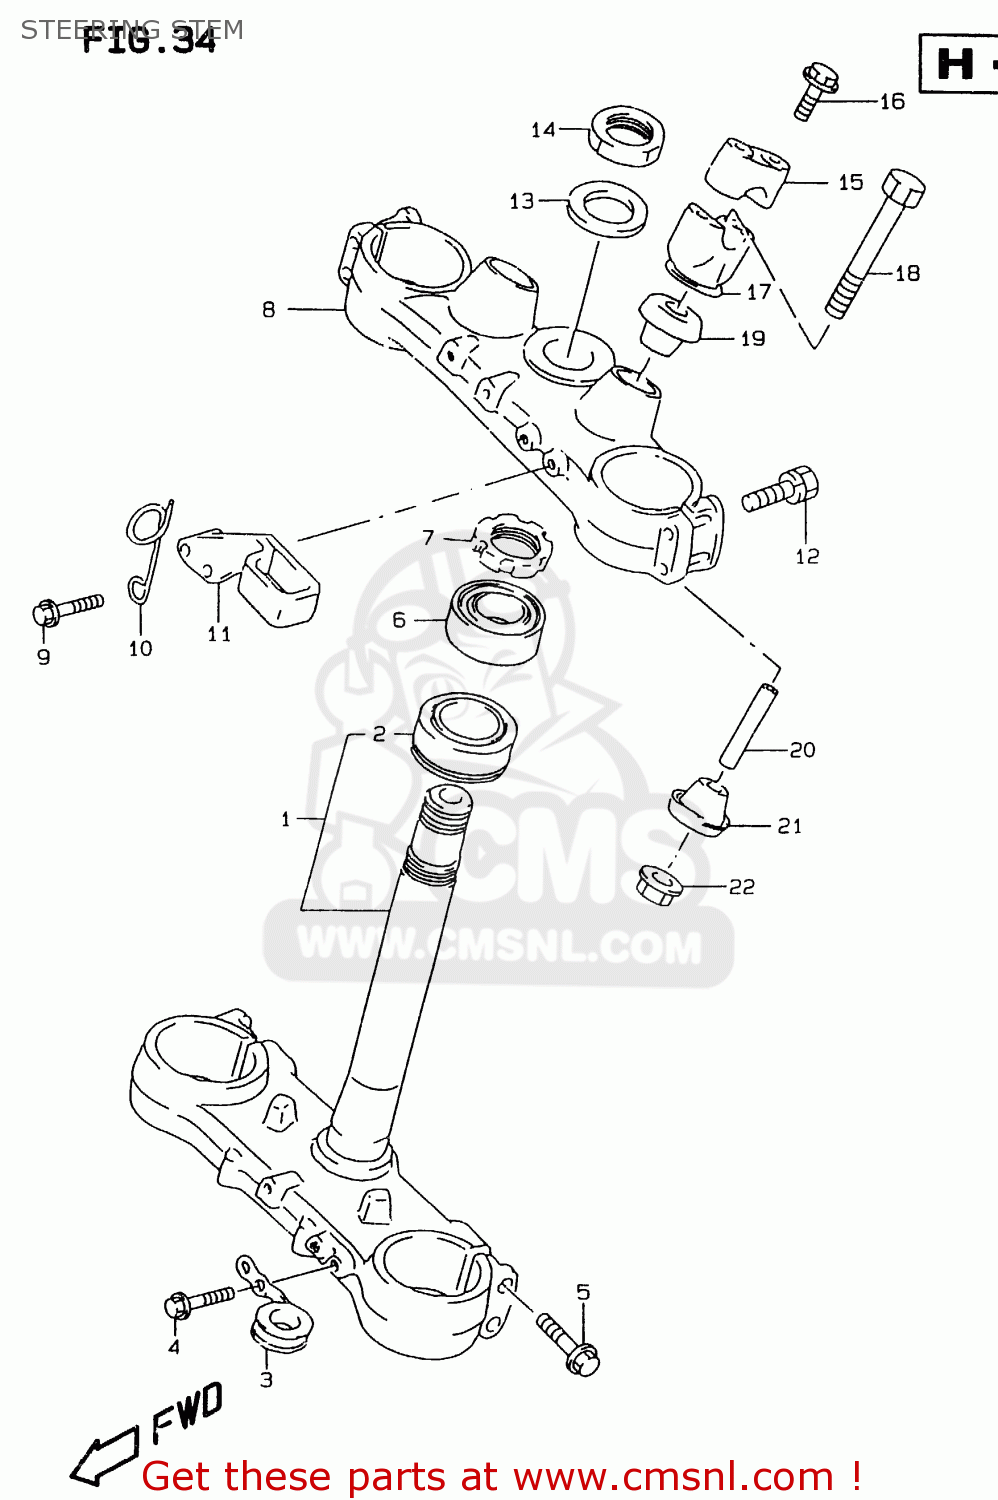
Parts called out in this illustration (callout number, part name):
1	STEM,STEERING
2	BEARING(30X52X16)
3	GUIDE,CABLE LWR
4	BOLT,PROTECTOR(6X10)
5	BOLT
6	BEARING(30X52X16)
7	NUT,STEERING
8	HEAD,STEERING STEM
9	BOLT,GUIDE
10	GUIDE,CLUTCH CABLE
11	GUIDE,HOSE
12	BOLT
13	WASHER,STEM HEAD
14	NUT,STEM HEAD
15	HOLDER,HANDLEBAR
16	BOLT,HANDLE HOLDER(8X35)
17	HOLDER,HANDLE UNDER
18	BOLT,HANDLE HOLDER(10X70)
19	CUSHION,RUBBER UPR
20	SPACER
21	CUSHION,RUBBER UNDER
22	NUT
